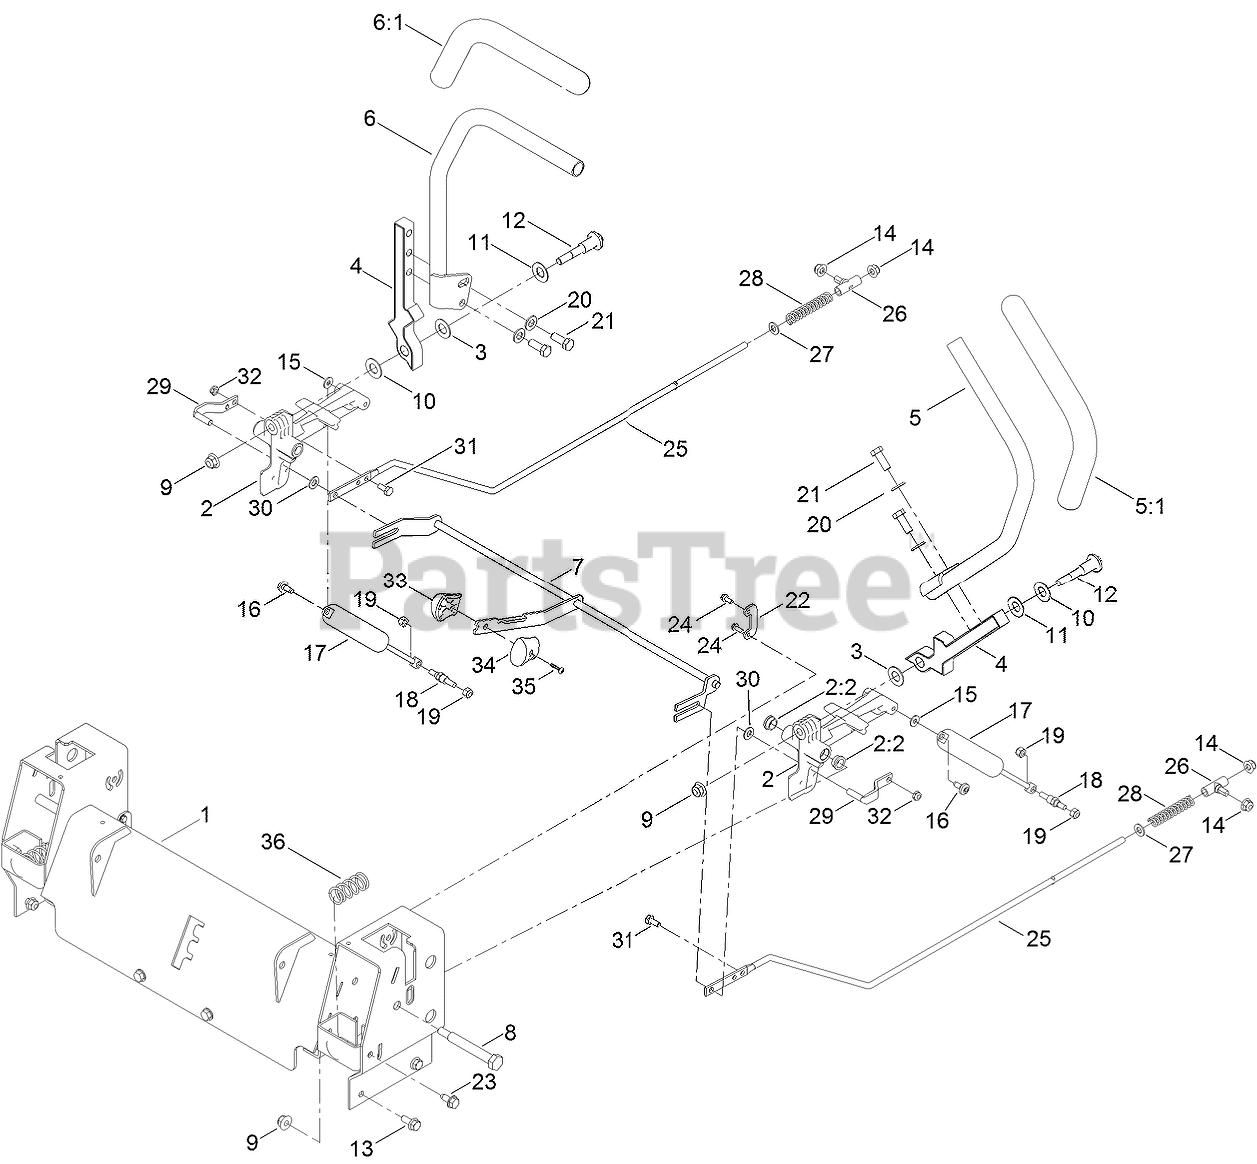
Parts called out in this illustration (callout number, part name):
1	CONTROL BOX ASM
2	ACTUATOR ARM ASM
2:2	BUSHING-FLANGE
3	WASHER-NYLON
4	ARM-CONTROL
5	HANDLE-CONTROL, LH
6	HANDLE-CONTROL, RH
7	SPEED CONTROL ASM
8	BOLT-PIVOT
9	NUT-HF, NI
10	WASHER
11	WASHER-BELLEVILLE
12	BOLT-PIVOT
13	SCREW-HHF
14	NUT-HF, NI
15	WASHER
16	SCREW-SHOULDER
17	DAMPER
18	STUD-DAMPER
19	NUT-LOCK, NI
20	WASHER-FLAT
21	SCREW-HH
22	RETAINER
23	SCREW-HWHTF
24	SCREW-TAPTITE
25	ROD-HYDRO
26	MOUNT-ROD, HYDRO
27	WASHER-PLAIN
28	SPRING-RETURN, NEUTRAL
29	PIN-ROD, HYDRO
30	SPACER-NYLON
31	SCREW-HH
32	NUT-LOCK, NI
33	KNOB-RH
34	KNOB-LH
35	SCREW-PPH
36	SPRING-RETURN
